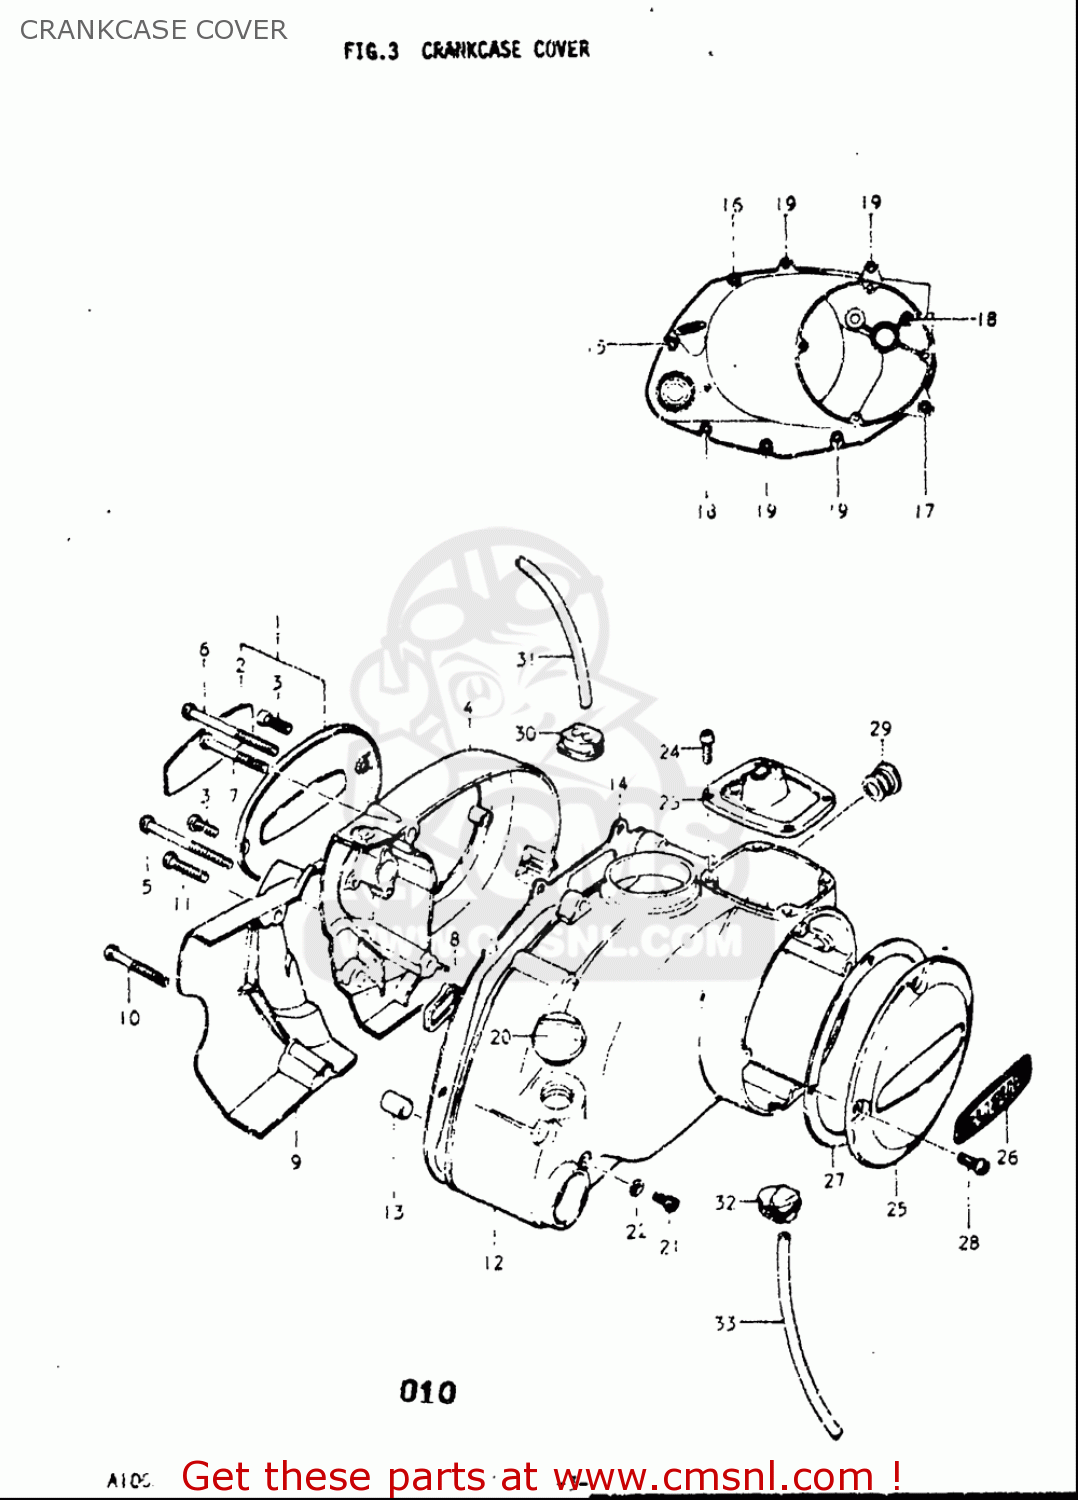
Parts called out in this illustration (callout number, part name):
2	EMBLEM,CONTACT BREAKER CAP
3	SCREW
5	SCREW
6	SCREW
7	SCREW
10	SCREW
11	SCREW
13	PIN
14	GASKET,CLUTCH COVER (NAS)
15	SCREW
16	SCREW
17	SCREW
18	SCREW
19	SCREW
20	PLUG
21	SCREW(6X10)
22	GASKET(6.2X11X1) (NAS)
23	COVER,CARBURETOR TOP
24	SCREW
26	EMBLEM,CONTACT BREAKER CAP
28	SCREW
29	Plug
30	GROMMET
31	HOSE(3X5X600)
32	GROMMET
33	HOSE(3X5X600)
